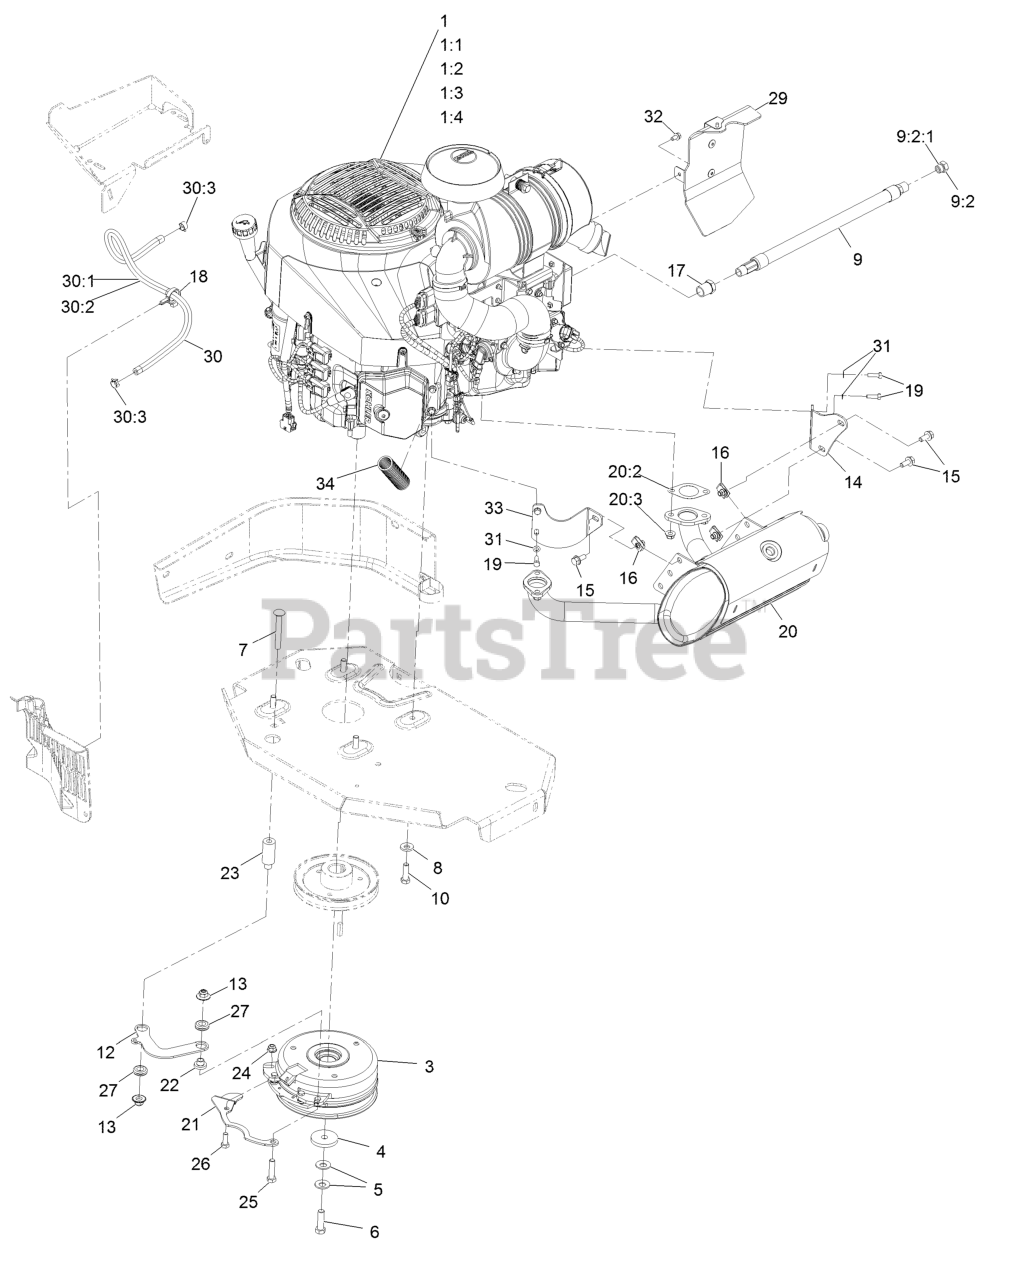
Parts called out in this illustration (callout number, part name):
1:1	Kohler 52 050 02-S Engine Oil Filter
1:2	Kohler 25 083 01-S Engine Air Filter
1:3	Kohler 25 083 04-S Safety Filter
1:4	Kohler 25 050 42-S Fuel Filter
3	Clutch Kit
4	Washer-Clutch
5	Washer-Spring Disc 7/16
6	Screw-HH 7/16-20 X 1 1/2 W/Loctite
7	Bolt-Carriage 3/8-16 X 3
8	Washer-Spring Disc 3/8
9	Oil Drain Hose ASM
9:2	Plug-W/O-Ring
9:2:1	O-Ring
10	Screw-HH 3/8-16 X 1 1/4
12	Link-Anchor, Clutch
13	Nut-Nyloc 3/8-16 Flg
14	Bracket-Muffler
15	Screw-HH Flg 5/16-18 X 3/4
17	Bushing
18	Clamp-Hose
19	Screw-HH M6-1 X 20Mm W/Patch
20	Muffler Kit
20:2	Gasket-Exhaust
20:3	Nut-Flange, Lock
21	Belt-Guide
24	Nut-Nyloc 5/16-18 Flg
25	Screw-HH 3/8-16 X 1 1/2
26	Screw-HH 5/16-18 X 7/8
27	Grommet-Rubber
29	Rear Baffle ASM
30	Fuel Line ASM
30:1	Hose-Fuel Line 29"
30:2	Sleeve, Thermal
30:3	Clamp-Hose
31	Washer-Spring Disc 1/4
32	Screw-HWH M6-1 X 12Mm Tf
33	Bracket-Muffler, Front
34	Conduit-Convoluted
